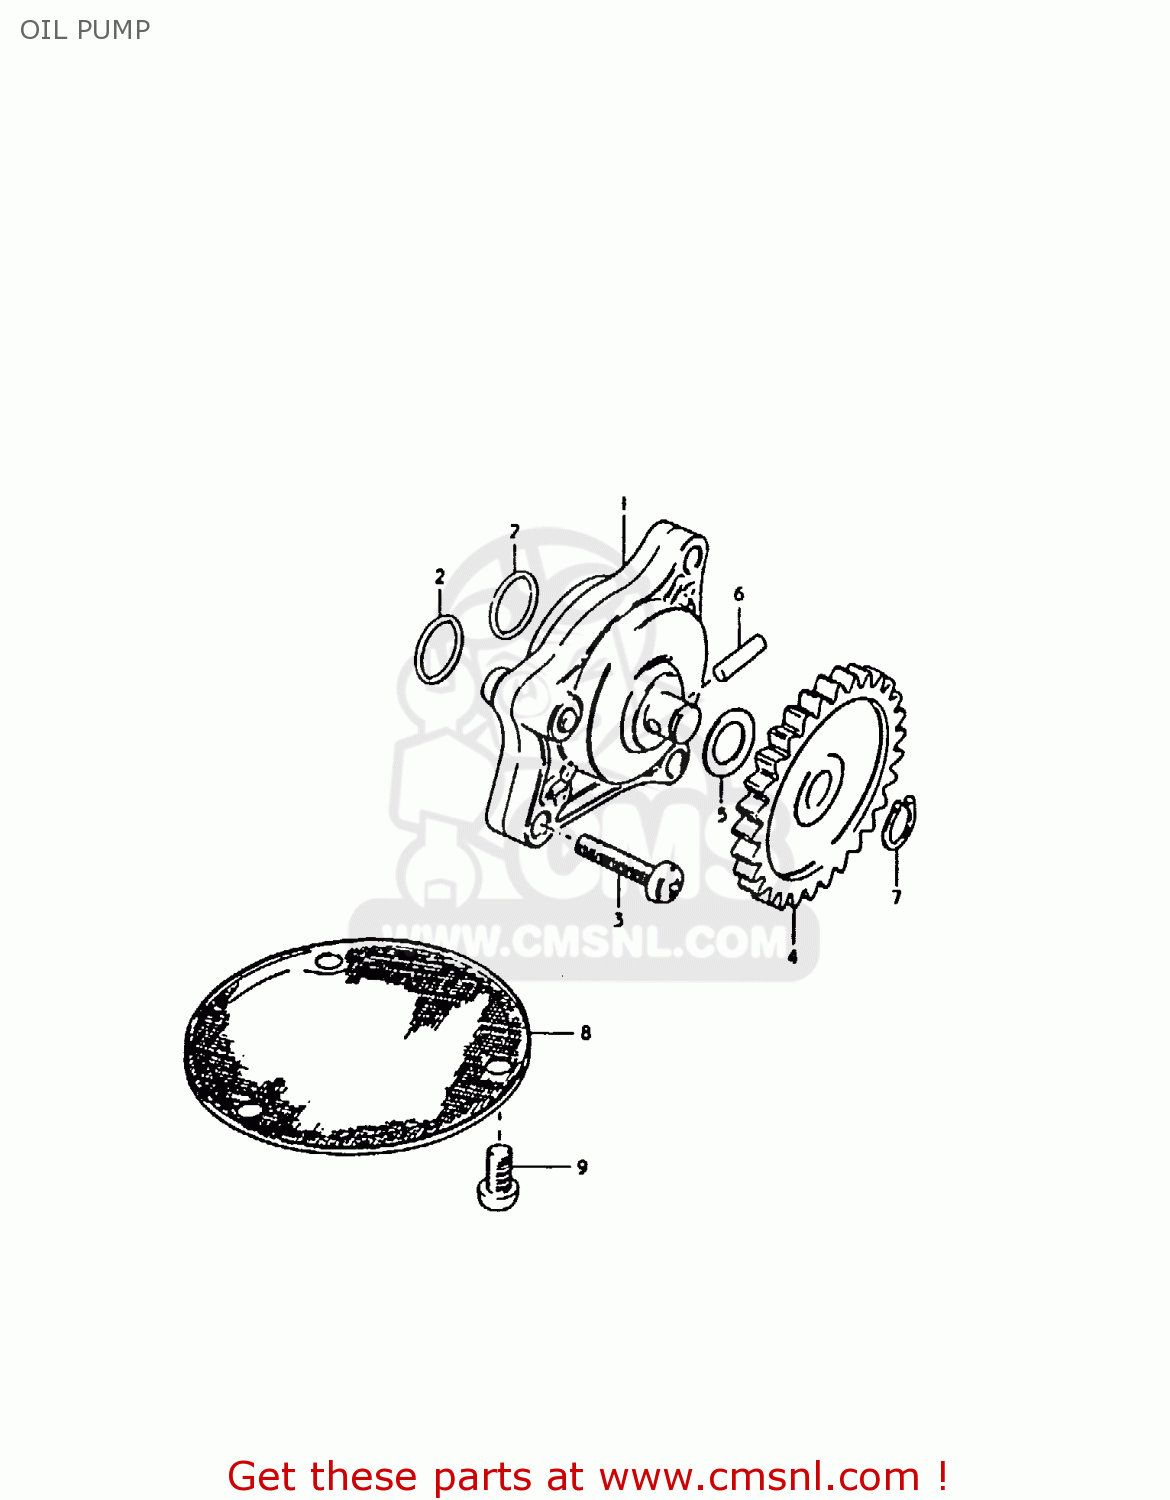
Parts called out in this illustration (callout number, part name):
1	PUMP ASSEMBLY,OIL
2	O RING(D:1.9,ID:13)
3	SCREW
4	GEAR,OIL PUMP DRIVEN
5	SHIM
6	PIN(4X15.8)
7	CIRCLIP
8	STRAINER,ENGINE OIL
9	SCREW 6X12
